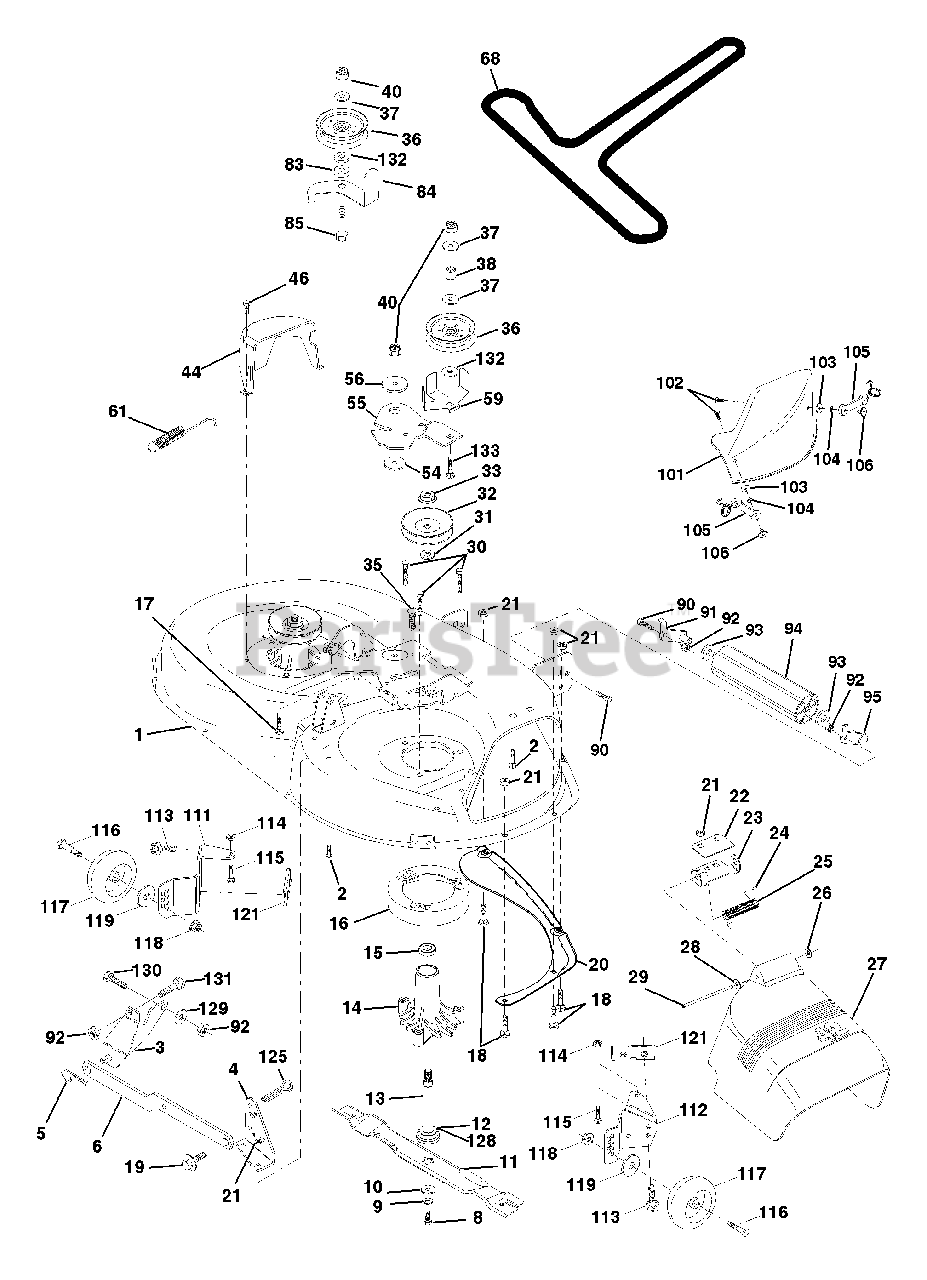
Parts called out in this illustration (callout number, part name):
1	Housing Asm Mower 42" 94 T-Path
2	Bolt Rdhd Sqnk 5/16-18 unc X 3/4
3	Bracket Asm Fr Sway Bar 38/42
4	Bracket Asm Deck 42" sway Bar
5	Retainer Spring
6	Arm Suspension Rear
8	Bolt 3/8-24 x 1 25 Gr 8 Patched
9	Washer Lock Hvy 3/8 Unplated
10	Washer Hard Blade Mower Vented
11	Blade Mower Mulching 42"
12	Bearing Ball #6204 (Mandrel)
13	Shaft Asm W/lower Bearing
14	Housing Mandrel Vented (machd)
15	Bearing Ball Mandrel
16	Stripper Round Mower
17	Bolt Rdhd Sqnk 3/8-16 X 2-1/4
18	Bolt Carr 5/16-18 X 5/8
19	Bolt Shoulder
20	Baffle Vortex 42
21	Nut Crown Lock 5/16-18
22	Stiffener Bracket 42" deck
23	Bracket Deflector Mower 42"
24	Cap Sleeve 80 x 112 Blk Mower
25	Spring Torsion Deflector 2 52
26	Nut Push Phos & Oil
27	Shield Deflector Mower 42" Blk
28	Washer 11/32 X 5/8 X 16 Ga
29	Rod Hinge 42" 6 75 Wlg
30	Screw Thdrol Washer Head
31	Washer Spacer Mower Vented
32	Pulley Mandrel 42"
33	Nut 9/16 top Lock Flng Cntr
35	Fastner Christmas Tree
36	Pulley Idler Flat 3 060
37	Washer 13/32 X 13/16 X 16 Ga
38	Spacer Spring Stop Idler
40	Nut Lock 3/8-16 Unc
44	Guard Mandrel LH Black
46	Screw Thdrol 1/4-20 x 5/8
54	Washer Hardened
55	Arm Idler 42" mower LT/YT
56	Spacer Retainer Pm Mower
59	Guard, Belt
61	Spring Ext. Elect
68	V-Belt Mower
83	Washer Sintered
84	Keeper Belt Idler
85	Bolt Carriage 3/8-16 x 2-1/4 Gr.5
90	Bolt Fin Hex 3/8-16 unc X 1
91	Bracket Asm Noseroller LH
92	Nut Lock Hex w/ins. 3/8-16 UNC
93	Washer 17/32 X 7/8 X 16 Ga
94	Roller Nose 38 & 42
95	Bracket Asm Noseroller RH
101	Cover Mulching 42" Blk
102	Screw
103	Washer #10
104	Washer Lock #10
105	Latch Asm Bagger
106	Nut Weld .327/.304 #10-24
111	Bracket Wheel Gauge Lh 42" Deck
112	Bracket Gauge Wheel Rh 42" Deck
113	Screw Thdrol 5/16-18 x 3/4 TYT
114	Nut Keps 5/16 - 18 UNC
115	Bolt Carriage 5/16 - Unc x 1/2
116	Bolt Shld
117	Wheel Gauge Donut
118	Nut Centerlock 3/8 - 16 UNC
119	Washer 3/8 x 7/8 x 14 Ga.
125	Cotter Pin
128	Washer Felt
129	Washer 13/32 x 13/16 x 12 Ga.
130	Bolt Fin Hex 3/8-16 unc x 1 Gr. 5
131	Bolt Rdhd Sqnk 3/8-16 UNC
132	Washer 13/32 x 1-3/8 x 3 Ga.
133	Bolt RDHD 3/8-16 UNC x 2-3/4 Gr.5
